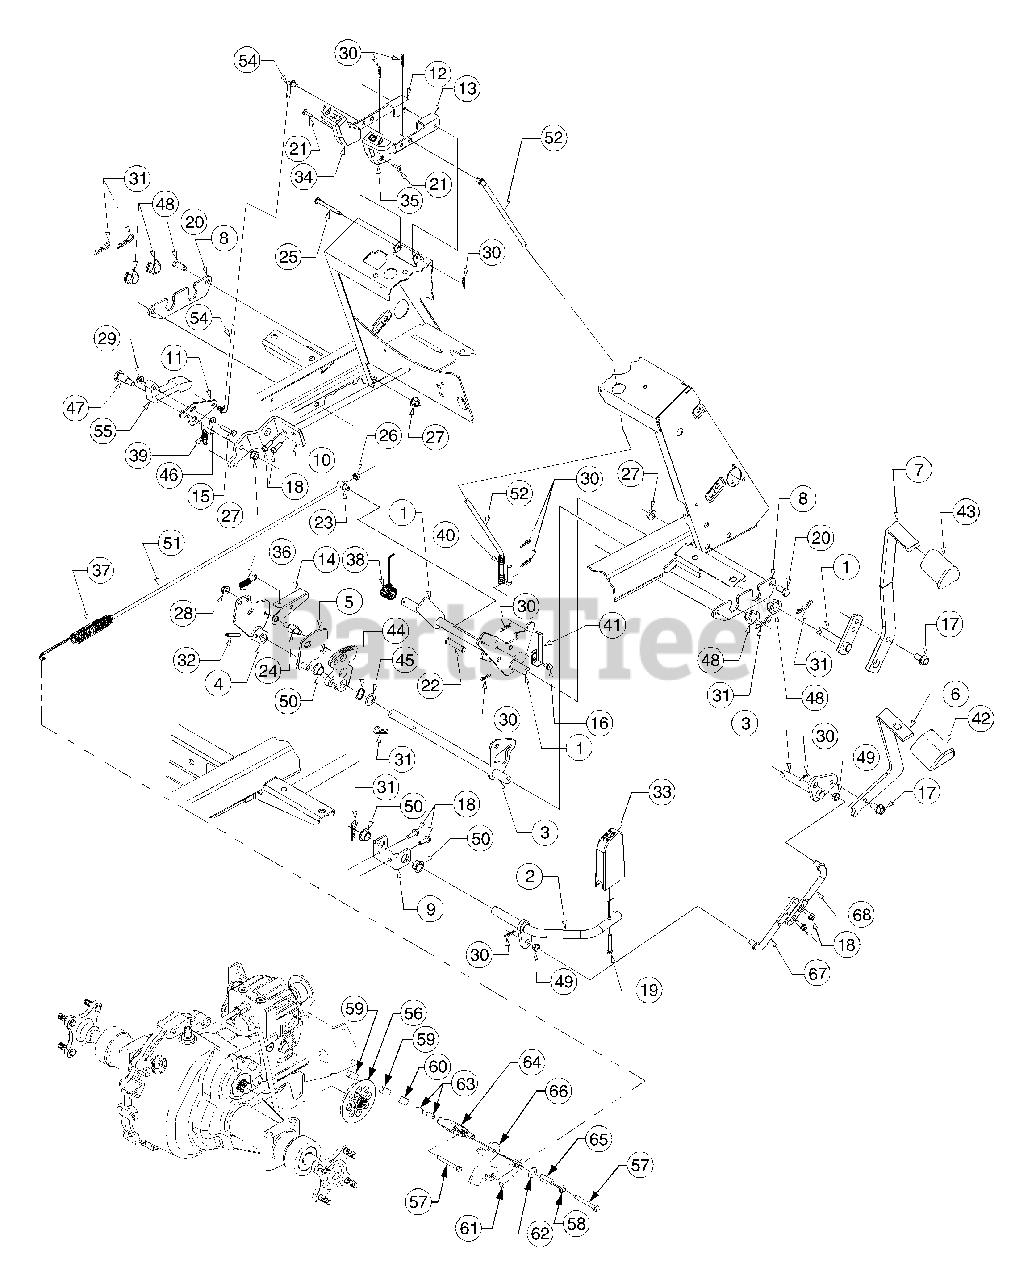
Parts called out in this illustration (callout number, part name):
1	Shaft Assy, Brake
4	Cam Assy, Control
5	Plate Assy, Disengagement
8	Plate, Bearing Mounting
10	Bracket, Cruise
11	Plate, Rod Adjustment
15	Screw, Hex Cap, 1/4-20 x 1.25
16	Screw, Hex Wash Hd Tapp 1/4-20 x .5
17	Screw, Hex Wash Hd Tapp 3/8-16x .75
18	Screw, Hex Wash Hd Tapp 1/4-20x .75
19	Screw, Truss Mach, #12 x 1.5
20	Screw, Hex Cap, 3/8-16 x .75 GR5
21	Screw, Phil Hd Pan, #10-24 x .75
22	Pin, Clevis, 3/8 x 1.62
23	Ferrule, Adjustment, 1/4-20 Thrd
24	Stud, Actuator
25	Pin, Clevis, .25 x 2.38
26	Nut, Hex Sems, 1/4-20
27	Nut, Hex Flange Lock, 3/8-16
28	Nut, Hex Flange Lock, 5/16-18
29	Nut, Hex Flange Lock, 1/4-20
30	Pin, Internal Cotter, 5/16 Dia x 1.12
31	Pin, Internal Cotter, 3/8 Dia x 1.62
32	Pin, Spiral Spring, 1/4 x 1.5
33	Pedal, Reverse
34	Knob, Cruise
35	Knob, Brake Lock
36	Spring, Extension, .38 OD x 2.1
37	Spring, Extension
38	Spring, Torsion
39	Spring, Extension, .6 OD x 1.34
40	Spring, Compression, .50 x 2.23
41	Spring, Switch Actuator
42	Pad, Forward Foot Control
43	Pad, Brake Foot
44	Washer, Wave, .625 x .885 x .015
45	Washer, Flat, .635 x 1.0 x .020
46	Washer, Flat, 1/4 x .63 x .051
47	Shoulder Bolt, .50 OD x .840
48	Bearing, Hex Flange Split
49	Bearing, Flange, .375 x .58 x .25
50	Bearing, Flange, .626 x .93 x .344
51	Rod, Brake
52	Rod, Parking Brake
54	Rod, Cruise
55	Latch, Cruise
56	Disc, Brake
57	Screw, Hex Wash Hd, Tapp, 1/4-20 x 2.375
58	Nut, Hex Nylon Lock, 5/16-24
59	Pad, Brake
60	Plate, Puck
61	Spring, Torsion
62	Washer, Flat, .343 x .88 x .062
63	Pin, Brake Actuating
64	Yoke, Brake
65	Bracket, Brake Anti Rotation
66	Arm, Brake Actuator
67	Rod, Rear Connecting
68	Rod, Front Connecting
